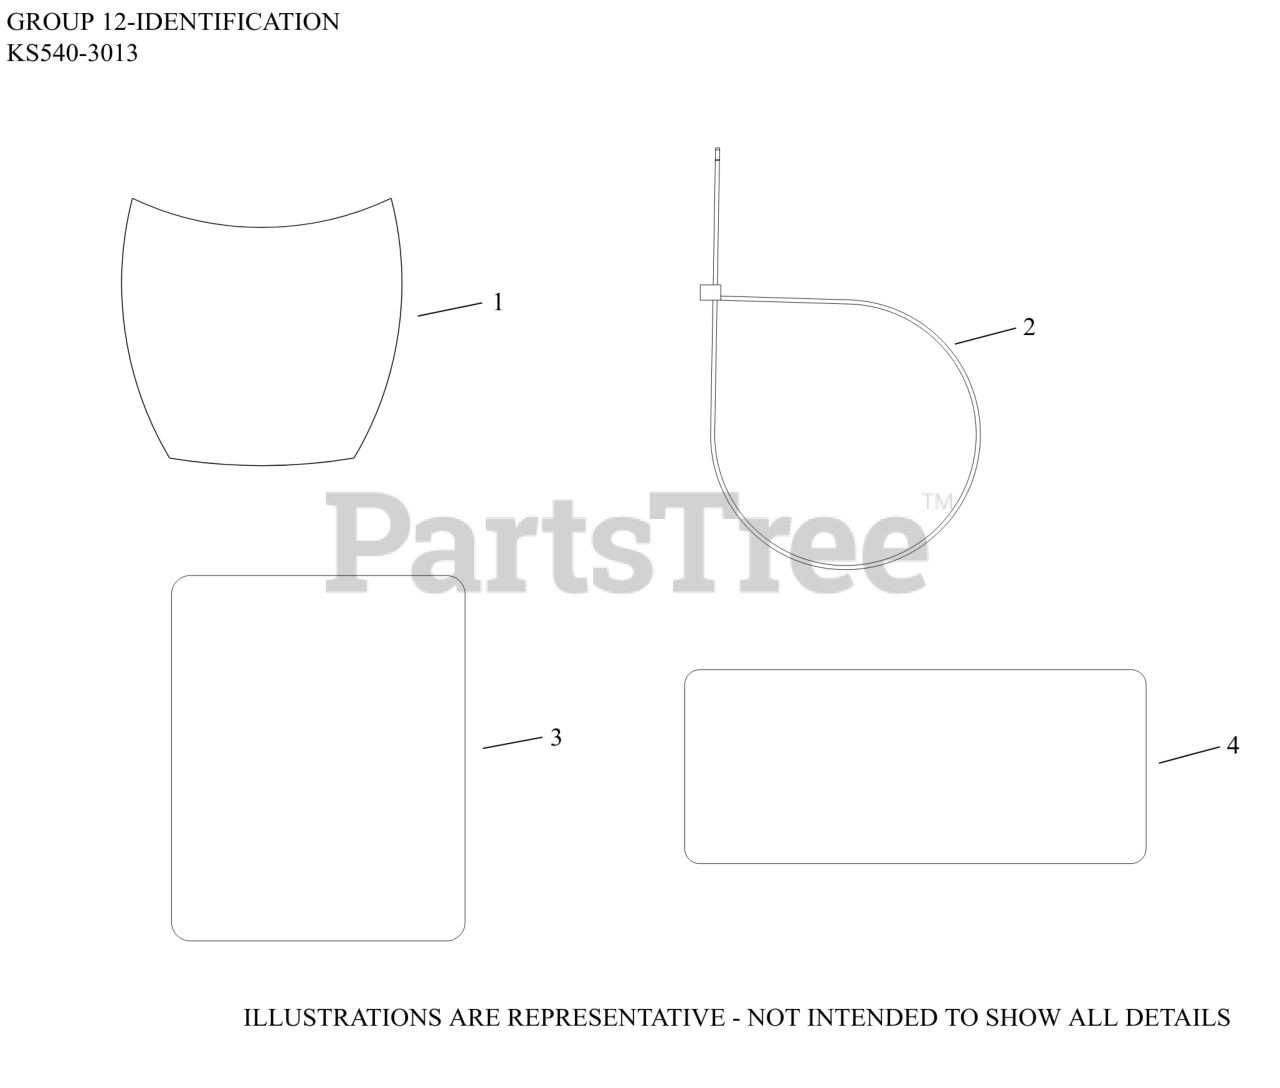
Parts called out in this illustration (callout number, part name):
1	LABEL, 18 HP STD AIR FILTER
3	LABEL, CLEAR LAMINATION
NI	DECAL, WARNING
